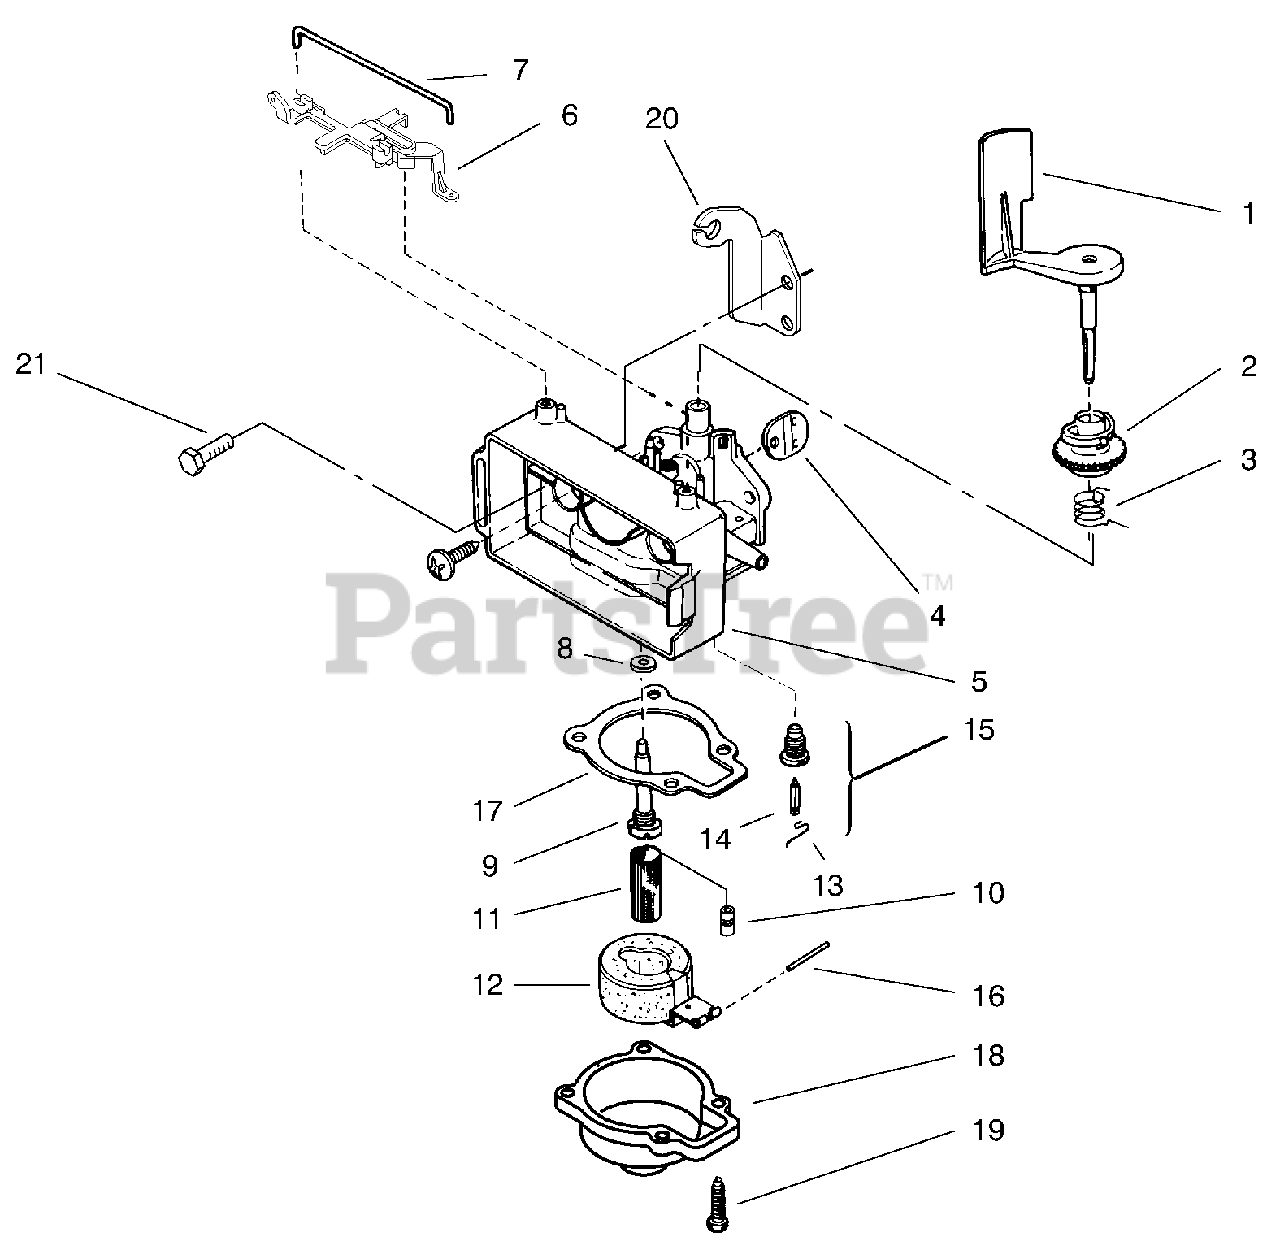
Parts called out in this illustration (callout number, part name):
1	Air Vane & Shaft
2	Collar Adjustment
3	Spring Governor
4	Disc Throttle
5	Carburetor Body
6	Lever-Speed Adjust
7	Retainer
11	Filter-Fuel
12	ASM-Float & Arm
13	Clip
14	ASM-Float
15	ASM-Seat
17	Gasket-Float Chamber
18	Float Chamber
20	Throttle Control Brkt
